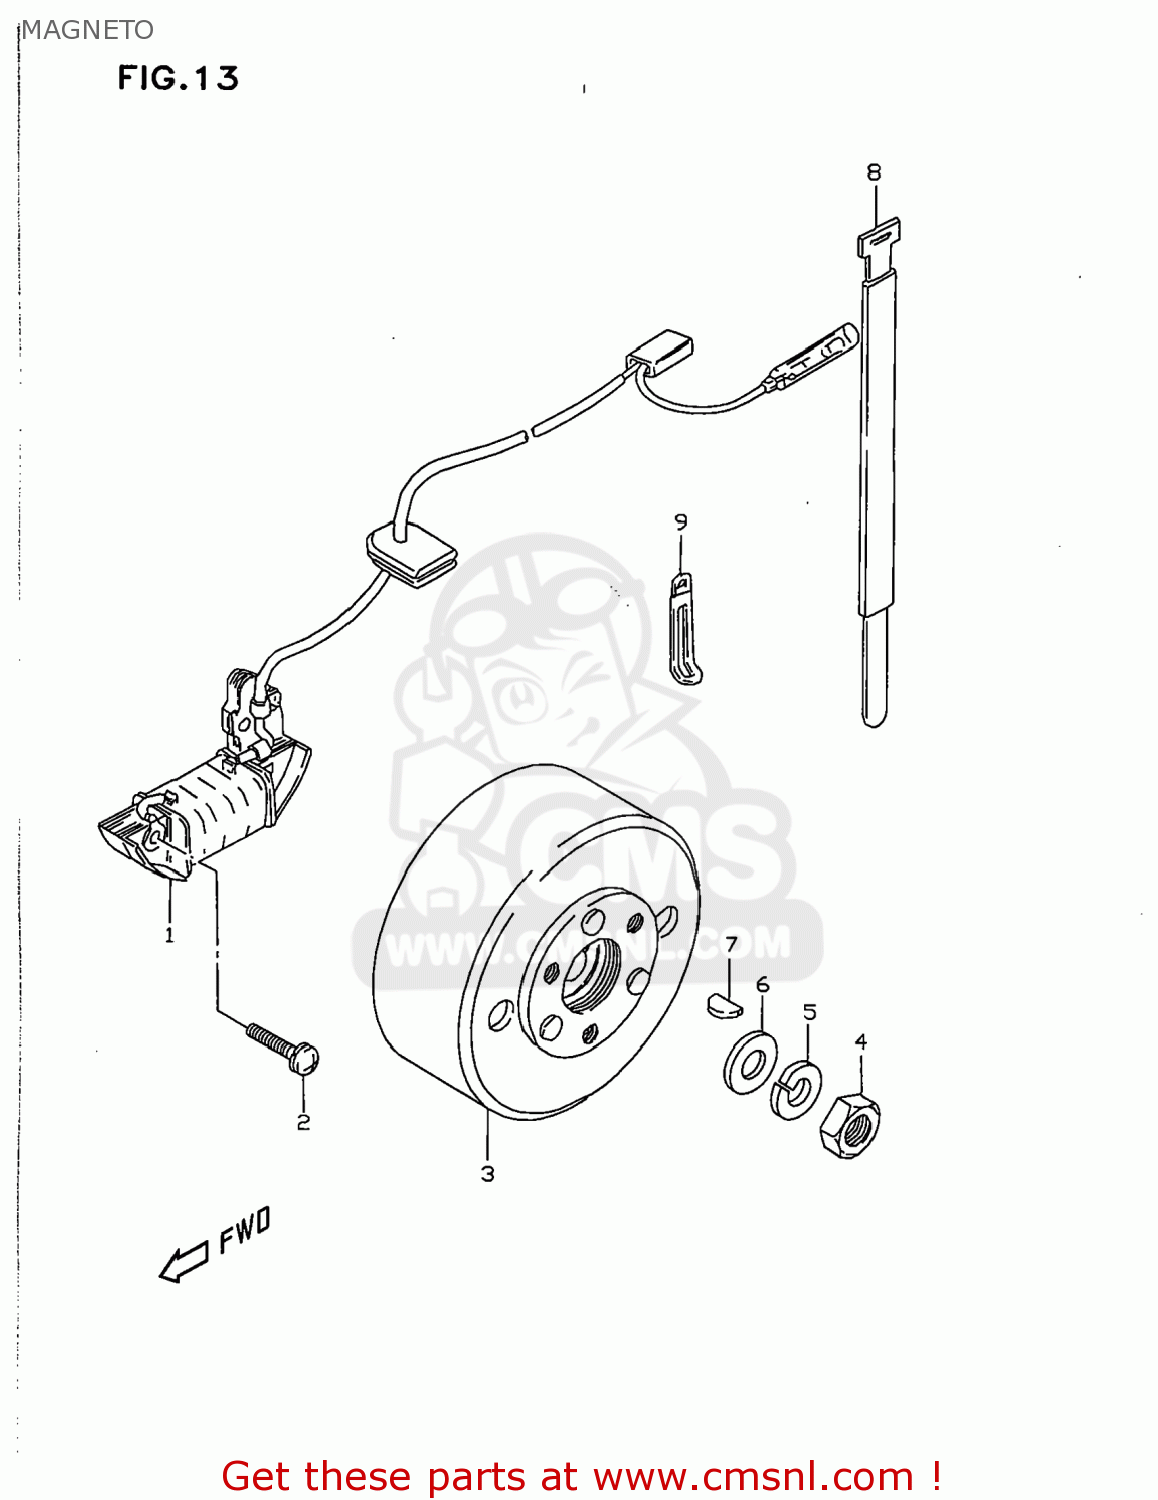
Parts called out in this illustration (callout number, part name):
1	COIL ASSY,IGNITION PRIMARY
2	SCREW
3	ROTOR ASSY
4	NUT
5	WASHER
6	WASHER
7	KEY
8	CLAMP
9	CLAMP(L:45)
